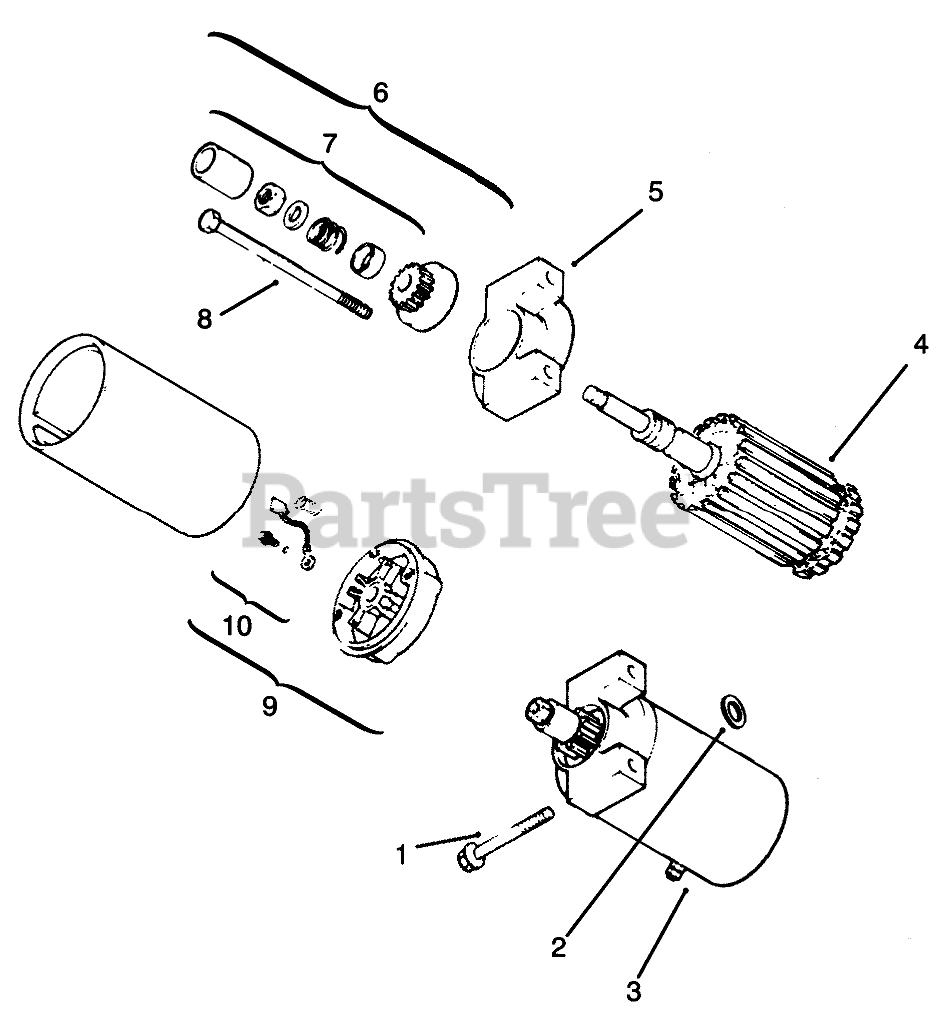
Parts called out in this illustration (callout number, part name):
1	Screw M8x1.25x70 (Only On: 72042, 72043, 72062, 72063)
2	Washer (Only On: 72042, 72043, 72062, 72063)
3	Starter ASM INCL 4-10 (Only On: 72042, 72043, 72062, 72063)
4	Armature (Only On: 72042, 72043, 72062, 72063)
5	Cap-Drive End (Only On: 72042, 72043, 72062, 72063)
6	Kit-Drive INCL 7 (Only On: 72042, 72043, 72062, 72063)
7	Kit-Drive Parts (Only On: 72042, 72043, 72062, 72063)
8	Screw-HF (Only On: 72042, 72043, 72062, 72063)
9	Cap-Commutator INCL 10 (Only On: 72042, 72043, 72062, 72063)
10	Kit-Brush And Spring (Only On: 72042, 72043, 72062, 72063)
